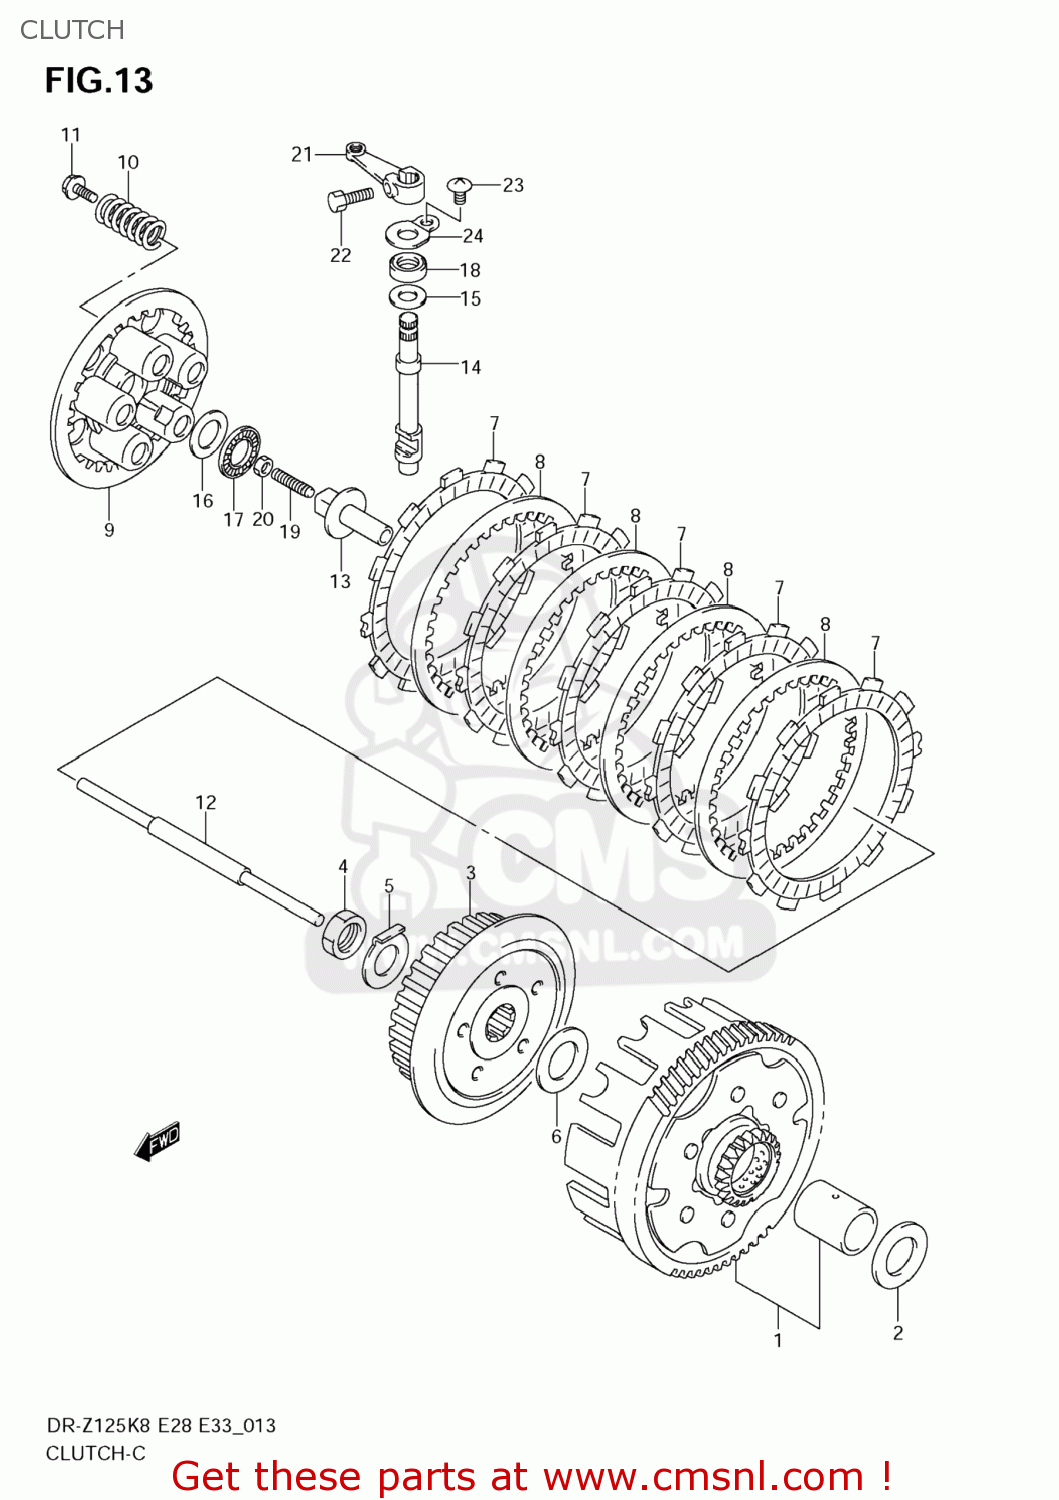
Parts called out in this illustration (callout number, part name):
1	GEAR ASSY,PRI DRIVEN(NT:59)
2	WASHER
3	HUB,CLUTCH SLEEVE
4	NUT
5	WASHER
6	WASHER
7	PLATE,CLUTCH DRIVE (NAS)
8	PLATE,CLUTCH DRIVEN (NAS)
9	DISC,CLUTCH PRESSURE
10	SPRING
11	BOLT(5X16)
12	ROD,CLUTCH PUSH
13	PIECE,CLUTCH PUSH
14	CAMSHAFT,CLUTCH RELEASE
15	SHIM(10X20X1)
16	WASHER(15.5X28X1)
17	BEARING(15X28X2)
18	SEAL,OIL(10X20X6)
19	SCREW(6X25)
20	NUT
21	ARM,CLUTCH RELEASE
22	BOLT
23	SCREW
24	RETAINER,CL RLSE OIL SEAL
